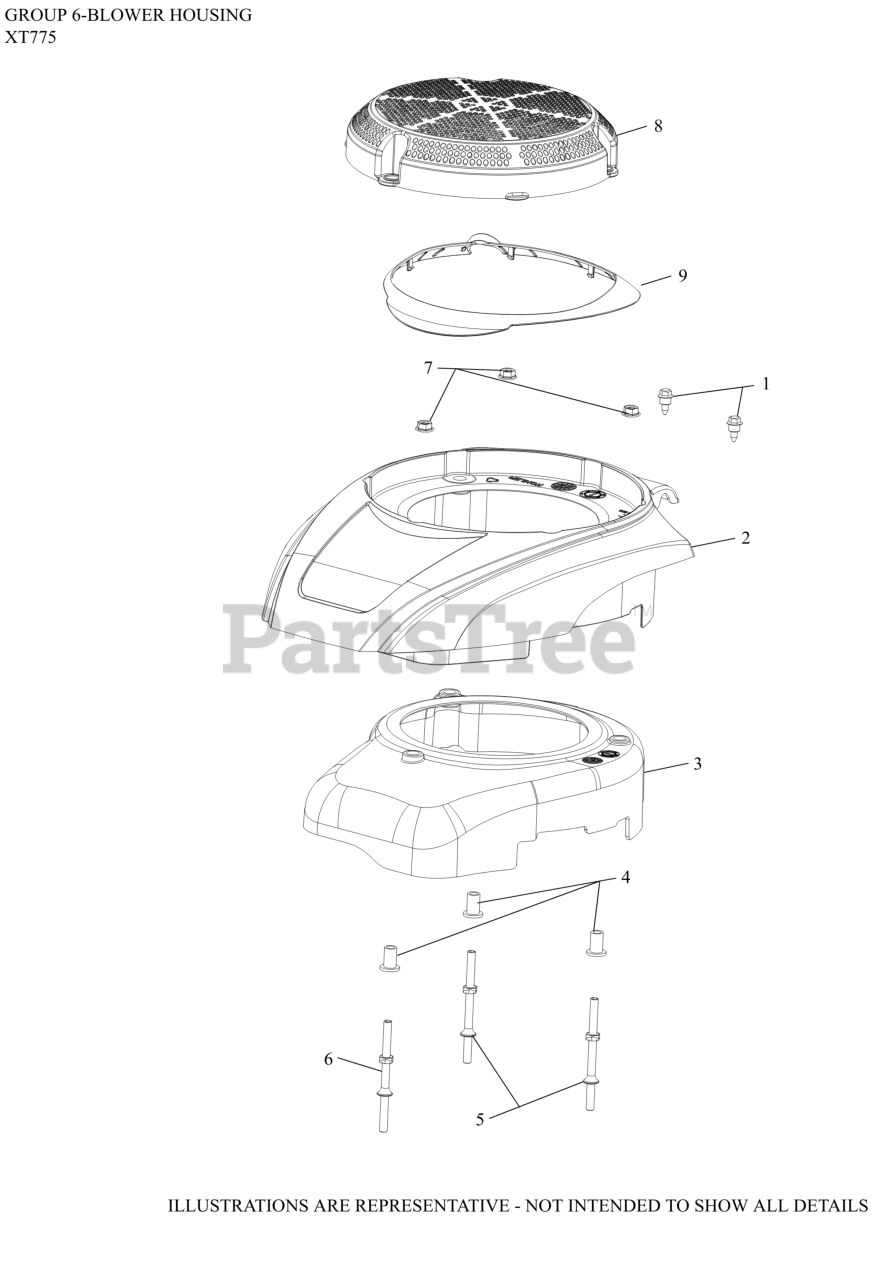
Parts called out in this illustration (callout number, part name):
2	COVER, ENGINE
5	STUD-USE 14 072 26-S
6	STUD-USE 14 072 25-S
7	NUT, HEX FLANGE (M6) - USE 14 100 16-S
